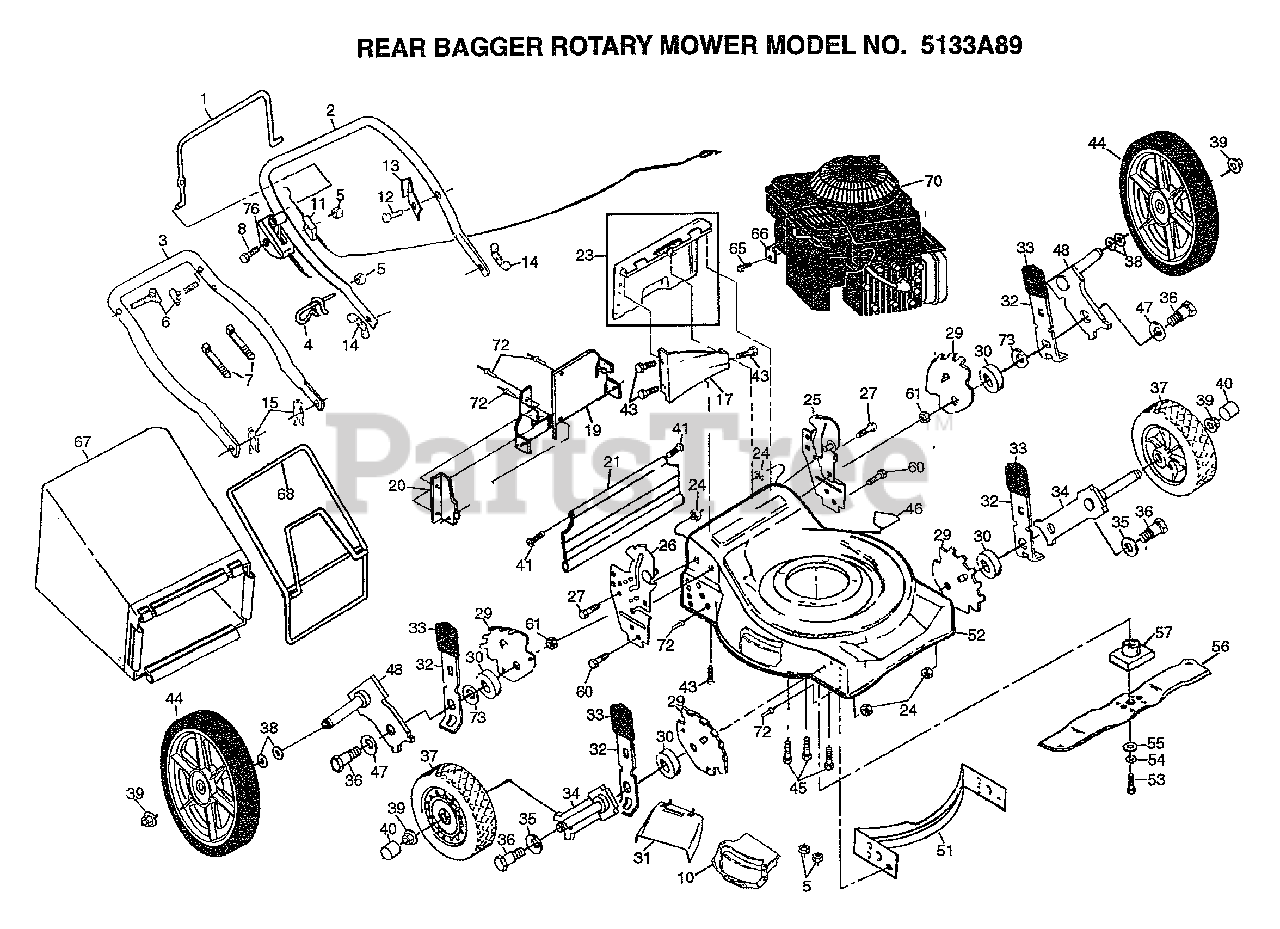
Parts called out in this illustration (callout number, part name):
1	CONTROL BAR PM
3	HANDLE LOWER
4	ROPE GUIDE
6	BOLT.HANDLE.LM
8	SCREW.HXHD.WASH.
10	DOOR ASM.MULCHER
11	"CABLE,ENG ZONE CO"
12	TAPPING SCREW
13	"BRKT,UPSTOP"
14	"NUT,WING PM"
15	HAIRPIN COTTER
17	REAR BAFFLE
19	PLATE.BACK.20RD
21	SKIRT.PUSH.20RD
23	KIT.DOOR.RR.20STL
24	LOCKNUT PM
25	HDLE BRKT ASSY LH
26	HDLE BRKT ASSY RH
27	SCREW.HXWS.5/16
29	BRKT.WHL.ADJ
30	SPACER.HEIGHT.ADJ
31	GUARD.DISCH.CLIPO
32	SPRING SELECTOR
33	KNOB PM
34	ARM.AXLE.ASM.BZP.
35	"WASHER, BELLEVIL."
36	BOLT SHLD 3/8-16
38	WAVE WASHER
39	HEX FLANGE LOCKNT
40	HUB CAP-PLASTIC
41	HINGE SCREW
43	SCREW
44	WHL & TIRE
45	BOLT.ENG.3/8-16
46	DECAL-DANGER PM
48	"AXLE ARM,REAR PM"
51	KIT.BAF.FRT.20RD
52	MOWER HSG KIT
53	SCREW
54	LOCKWASHER
55	"WASHER,HARDEN"
56	BLADE.20.MULCH.AY
57	BLADE ADAPTOR
61	LOCKNUT PM
65	SCREW PM
66	CABLE CLAMP
67	GRASS BAG
68	FRAME.CATCHER.ASM
72	BLIND RIVET
73	WASHER PM
76	"CONTROL, THROTTLE"
